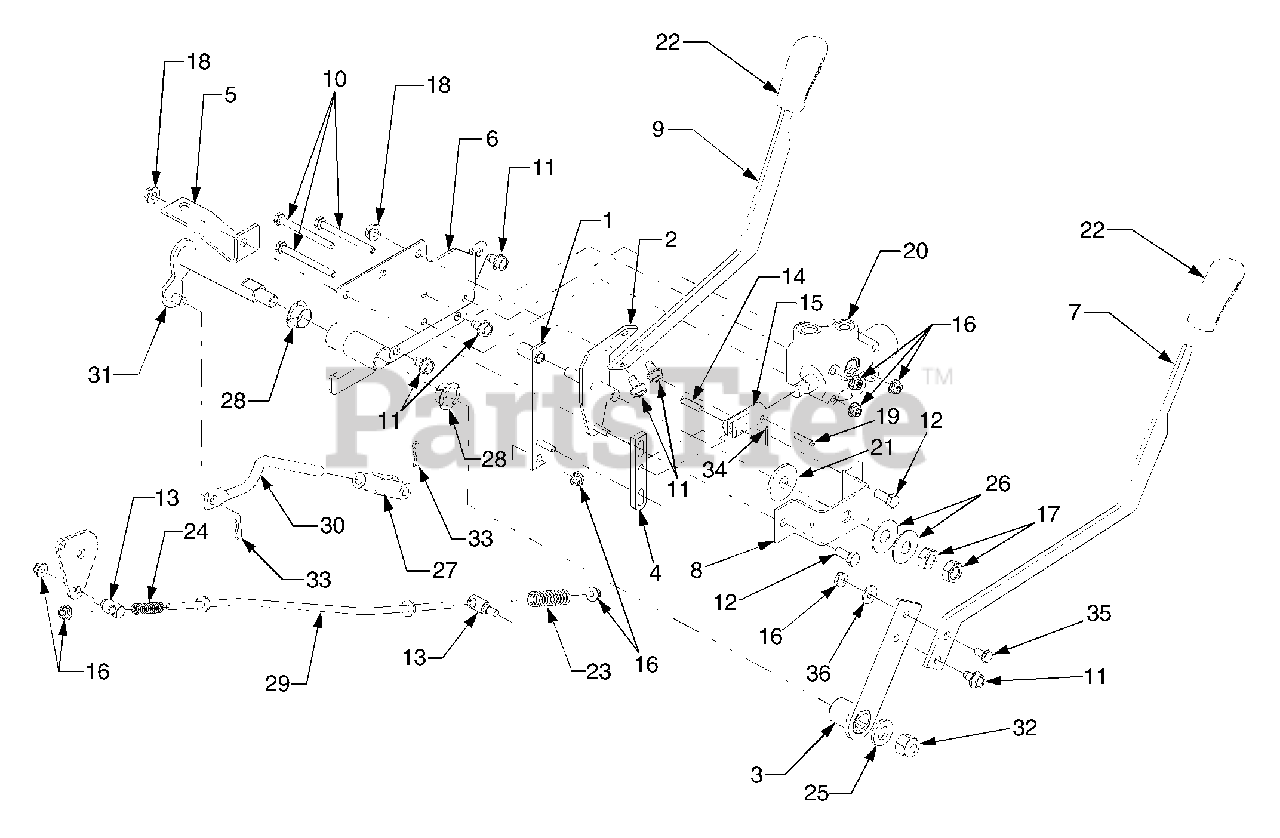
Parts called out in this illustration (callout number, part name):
1	Link Assembly, Feedback
2	Link Assembly, Input
3	Link, HI-LO Shifter
4	Link, Feedback
5	Bracket, Lift Brace
6	Bracket, Valve Mtg.
9	Handle, Lift
10	Screw, Hex Cap, 1/4-20 x 2.75 GR5
11	Screw, Hex Wash Hd. Tapp 5/16-18 x .5
12	Screw, Hex Cap, 5/16-18 x .75 GR5
13	Ferrule, Feedback Adjustment
14	Pin, Clevis, .25 x .937
15	Link, Valve
16	Nut, Hex Flange Nylon Lock 14-20 GRF
17	Nut, Hex Jam, 1/2-20 GR5
18	Nut, Hex Flange Lock, 5/16-18 GR5
19	Pin, Spirol, 3/16 x 1.0
20	Valve, Hydaulic Lift
21	Washer, Friction, .515 x 1.5 x .12
22	Grip, Handle
23	Spring, Compression
24	Spring, Compression
25	Washer, Flat, .531 x 1.062 x .134
26	Washer, Belleville, .53 x 1.375 x .06
27	Clevis, Adjustment
28	Bearing, Nylon Flange .75 ID
29	Rod, Feedback
30	Rod, Hi-LO Connecting
31	Shaft, Hi-Lo Shifter
32	Nut, Hex Nylon Lock, 1/2-20
33	Pin, Internal Cotter
34	Pin, Cotter, 1/16 x .75
35	Screw, Hex Cap, 1/4-20 x .5 GR5
36	Washer, Flat, .28 x .74 x .063
